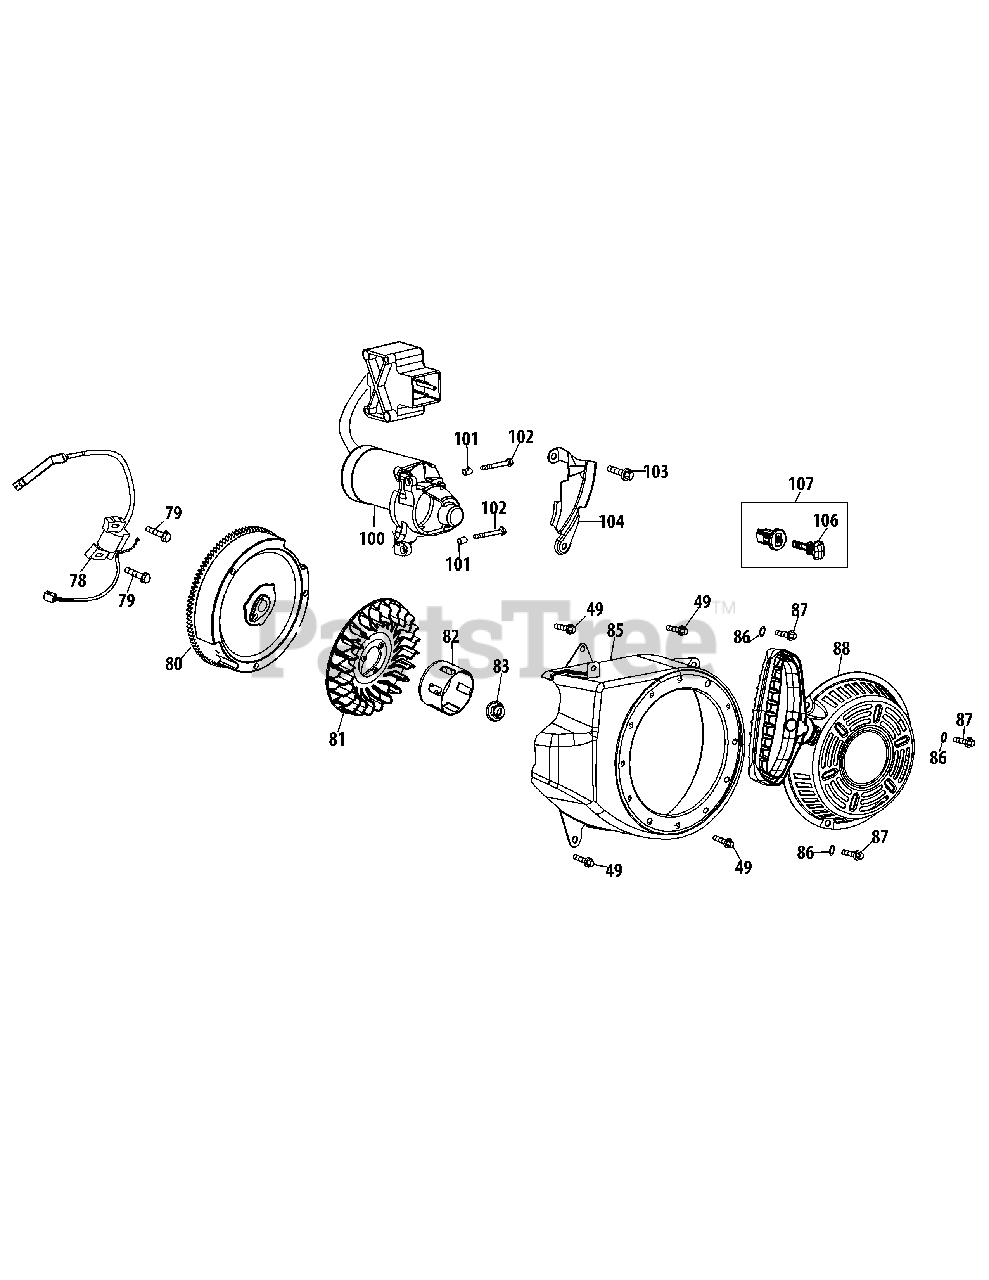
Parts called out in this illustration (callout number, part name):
49	Bolt M6×12
78	Ignition Coil Assembly
79	Bolt M6×25
80	Flywheel
81	Cooling Fan
82	Starter Cup
83	Nut, Special, M14×1.5
85	Blower Housing
86	Gasket 6
87	Bolt M6×10
88	Recoil Starter
100	Electric Starter
101	Dowel Pin 8×8
102	Bolt M6×32
103	Bolt M6×12
104	Blower Housing Shield
106	Key
107	Key Switch
